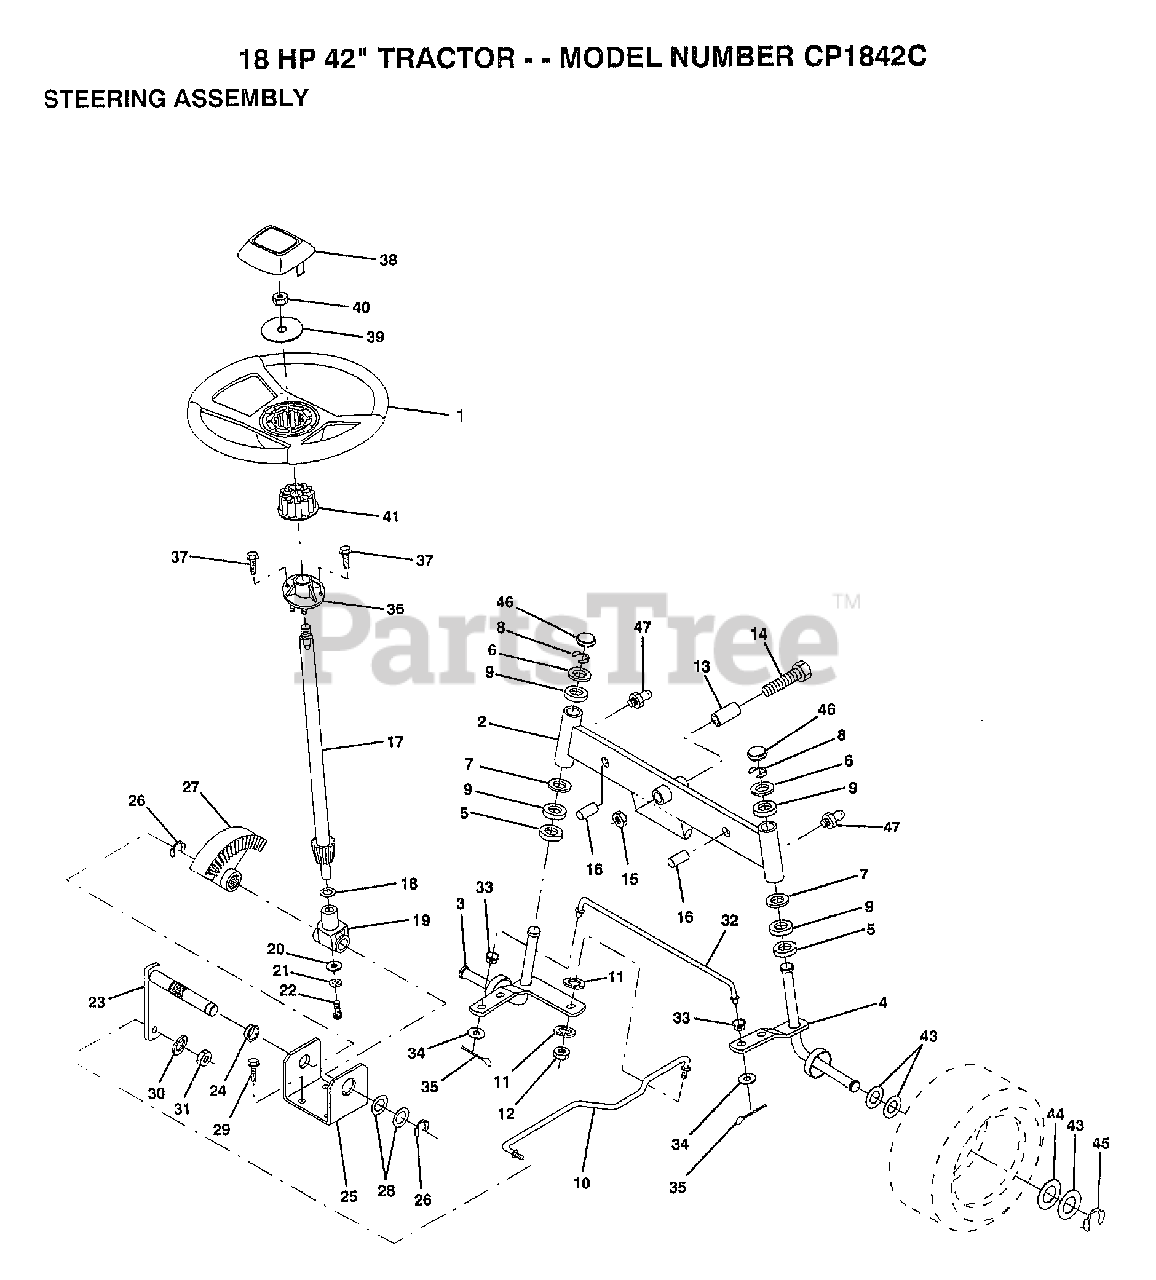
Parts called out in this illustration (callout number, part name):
3	SPINDLE LH
4	SPINDLE RH
5	WASHER .T
6	WASHER
7	WASHER
8	RING
9	COL. SRTG. BEAR.
11	LOCKWASHER
13	BEARING
14	BOLT HEX 5/8-11
16	AXLE PIN
17	STEERING SHAFT
18	THRUST WASHER
19	SUPPORT.SHAFT
21	LOCKWASHER
22	"SCREW,SPECIAL"
24	NYLINER T
25	"BRKT,STEERING"
26	RING
27	GEAR SECTOR
28	WASHER .T
29	SCREW
30	LOCKWASHER
32	TIE ROD
33	BUSHING.DRAGLINK
34	WASHER
35	COTTER PIN
38	"INSERT,STR WHEEL"
39	WASHER
41	ADAPTER LT
43	WASHER
44	WASHER
46	CAP
47	ZERK M
